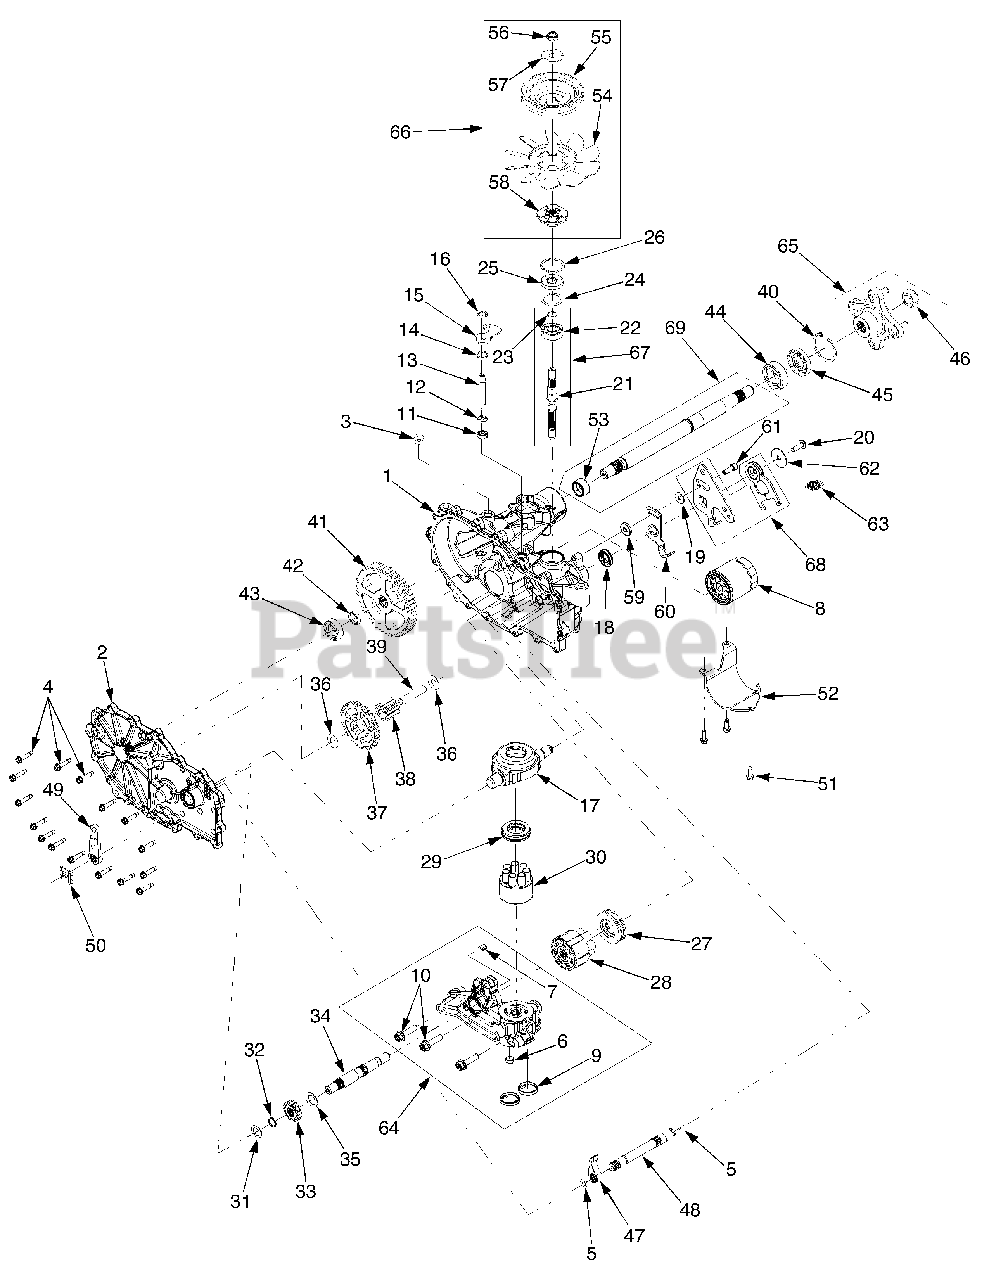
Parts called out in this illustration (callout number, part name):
1	Housing Assembly, Main LH .
2	Side Cover Assembly, LH
4	Screw, Hex Self Tapping, 1/4-20 x 1.25
6	Plug, Rubber
7	Plate, Bypass
8	Filter, Oil
9	Seal. Plug, 1.25 x .25
10	Screw, 3/8-16 x 1.5 Patched
11	Seal, Lip, .375 x .75 x .25
12	Ring, Retaining, .375 Ext.
13	Rod, Bypass
14	Ring, Retaining, .75 Int.
15	Arm, Bypass
16	Ring, Retaining, .375 Push ...
17	Swashplate, Trunnion
18	Seal, Lip, 18 x 32 x 7
19	Washer, Flat, 11/32 x 7/8 x 1/16
20	Screw, 5/16-24 x 1.0
21	Shaft, Input
22	Bearing, Ball, 17mm x 40 x 12
23	Ring, Wire Retaining, .561
25	Seal, Lip, 17 x 40 x 7
26	Ring, Retaining
27	Bearing, Thrust
28	Cylinder Block - Motor
29	Bearing, Thrust Ball
30	Block, Cylinder
31	Washer, Flat, 5/8 x 1.0 x .05
32	Ring, Retaining
33	Gear, 16T
34	Shaft, Motor
35	Washer, .71 x 1.16 x .04
36	Washer, HT, .5 x 1.0 x .032 ..
37	Gear, 43T
38	Gear, 11T
39	Pin, Jackshaft
40	Ring, Retaining, 2.06 Int.
41	Gear, 54T
42	Spacer, .75 x 1.0 x .257
43	Bearing, Ball, .75 x 40 x 12
44	Bearing, Ball, 1.0 x 52 x 15
45	Seal, Lip, 25 x 52 x 10
46	Nut, Hex Lock, 3/4-16
47	Pawl, Brake
48	Shaft, Inboard Brake
49	Handle, Brake
50	Clip, Retaining
51	Screw, Hex Cap, 1/4-20 x .75
52	Guard, Filter, LH
53	Spacer, .91 x 1.02 x .625
54	Fan, 7" 10 Blade
55	Pulley, 4.5
56	Nut, Hex Insert Lock, 1/2-20
57	Washer, OD Slotted
58	Hub
59	Spacer, .32 x 1.005 x .179
60	Arm, Neutral LH
61	Screw, Hx Patch, 5/16-24 x 1.0
62	Washer, .34 x1.5 x .062
63	Spring, Extension
64	Kit, Center Section LH
66	Kit, Fan-Pulley
67	Kit, Input Shaft
68	Kit, Return Assembly
69	Kit, Axle Shaft
